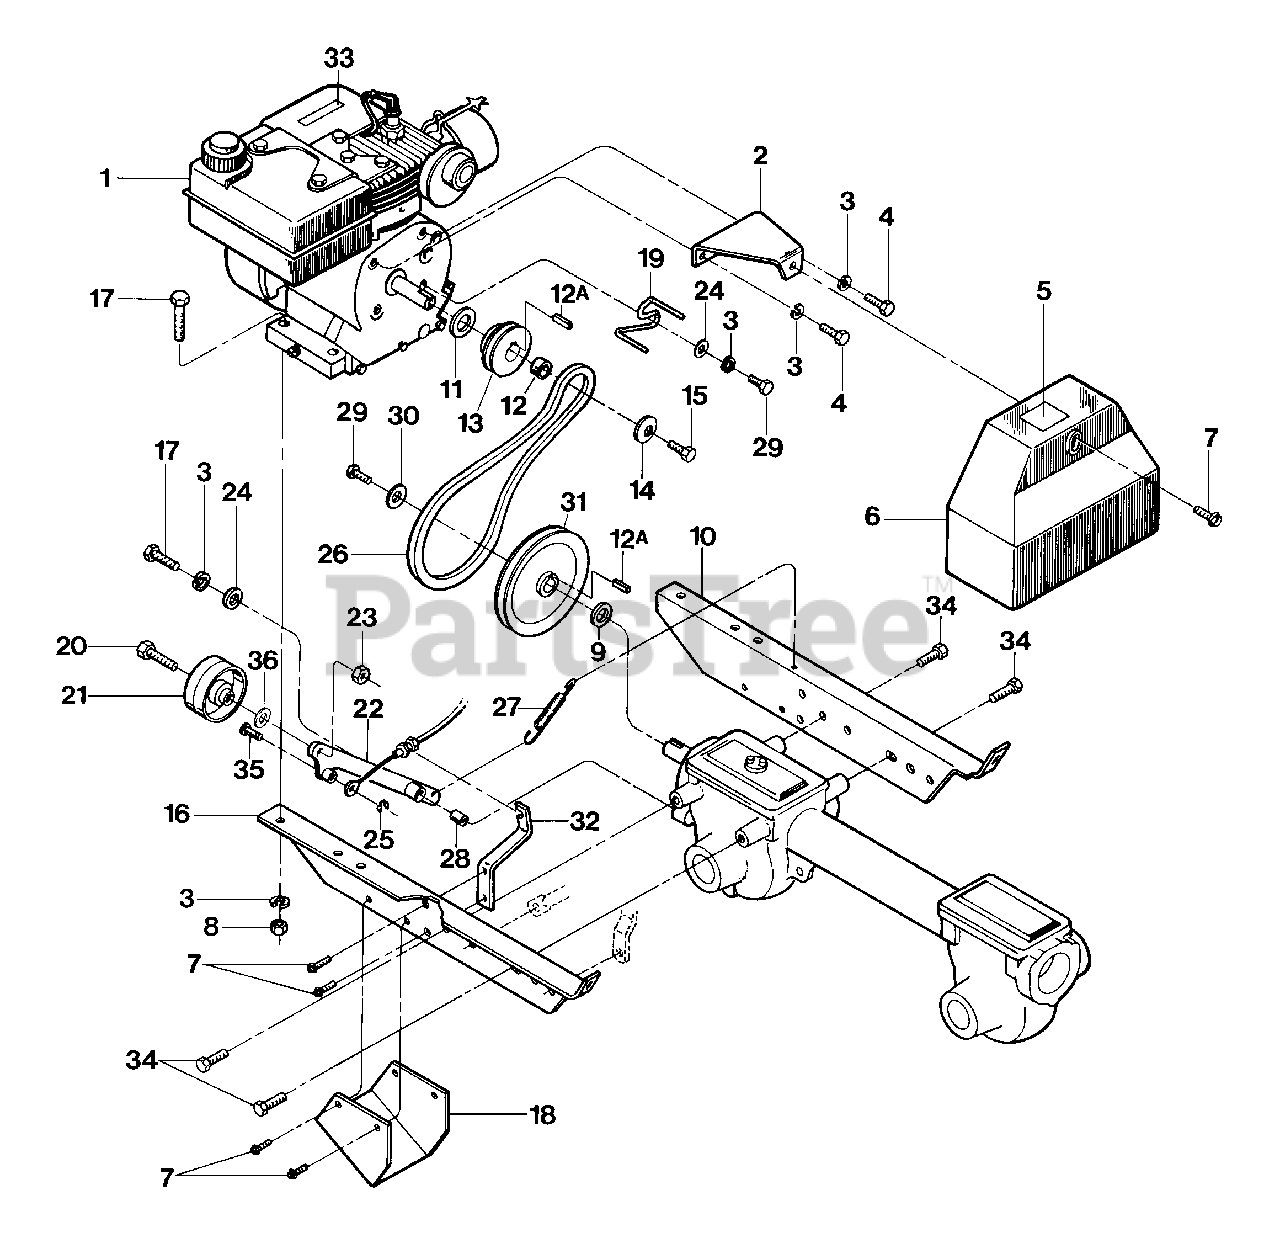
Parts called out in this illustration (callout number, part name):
1	Engine 3HP, recoil start
2	Bracket, Belt Cover
3	Lockwasher-5/16
4	Bolt-Hex Hd., 5/16-24 x 1/2
5	Decal-Warning, Hot Surfaces
6	Belt Cover-
7	Bolt-Flanged Hd., Self-Tapping, 1/4-20 x 1/2
8	Nut-Hex Hd., 5/16-18"
9	Support Washer
10	Bracket, Engine, Right
11	Shim
12	Spacer
12A	Key-3/16 x 1
13	Pulley, Engine Driven
14	Washer, Belleville
15	Bolt-Hex Hd., 3/8-24 x 1
16	Bracket, Engine, Left
17	Bolt-Hex Hd., 5/16-18 x 1-1/2
18	Belt Pulley Guard
19	Belt Guide
20	Bolt-Hex Hd., 3/8-16 x 1-1/2
21	Idler Pulley
22	Idler Lever
23	Locknut-3/8-16
24	Washer, Flat
25	Klip Ring
26	V-Belt
27	Spring, Return
28	Bushing-Idler Lever
29	Bolt-Hex Hd., 5/16-24 x 3/4, Grade 5
30	Washer, Belleville, Transmission Pulley
31	Pulley-Transmission
32	Bracket-Cable Mount
33	Decal-Stabilization
34	Bolt-5/16-18 x 5/8, Engine Bracket to Transmission
35	Clevis Pin-Control Cable
36	Washer-flat, 3/8
